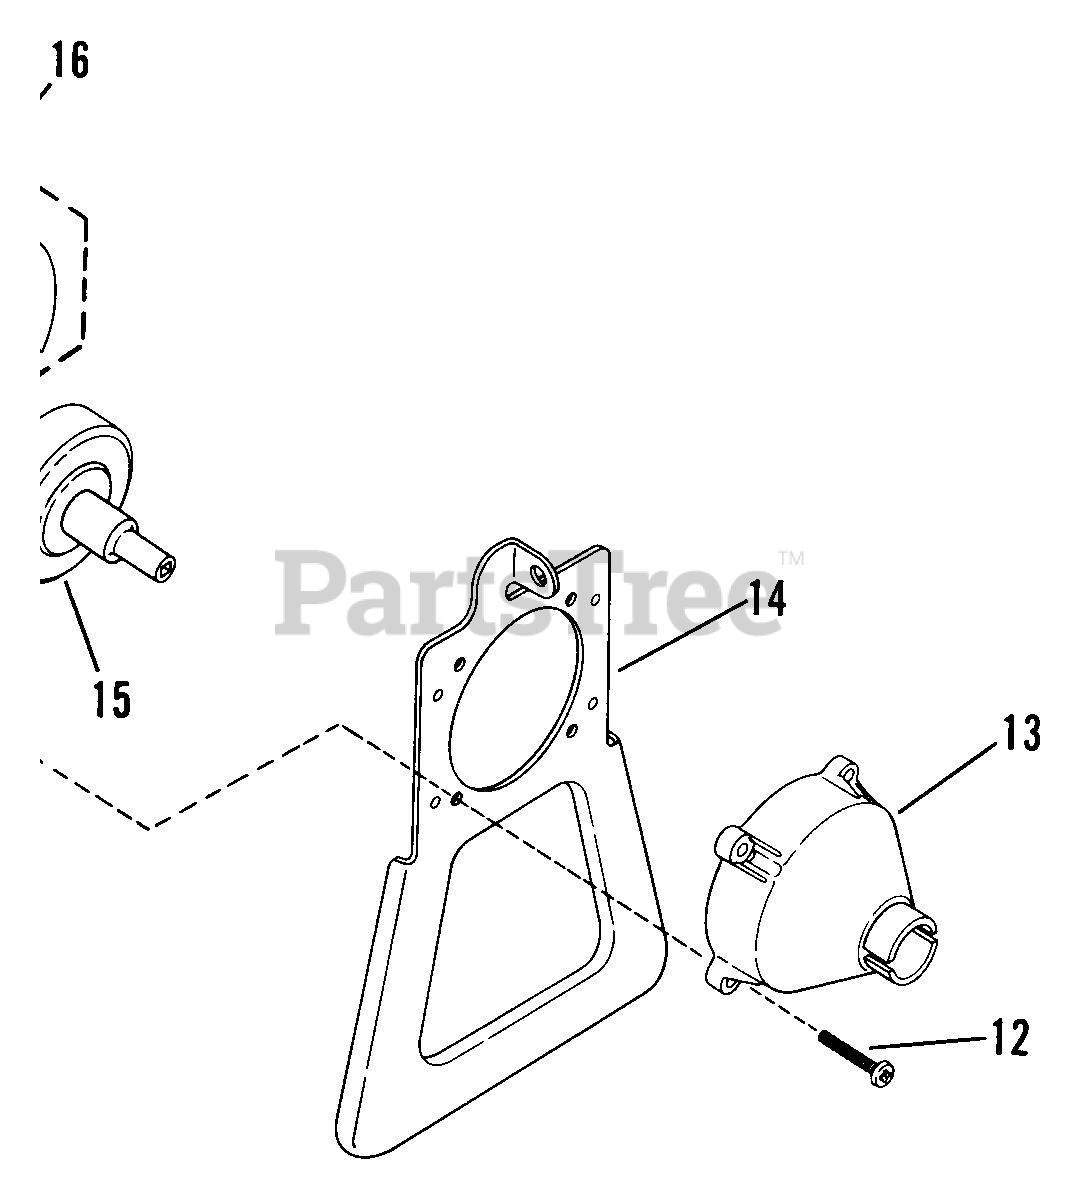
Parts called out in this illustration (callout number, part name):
12	SCREW, Cover, #10 x 1"
13	COVER, Clutch
14	STAND, Engine
15	DRUM,CIutch
16	CLUTCH SHOE, Assembly
